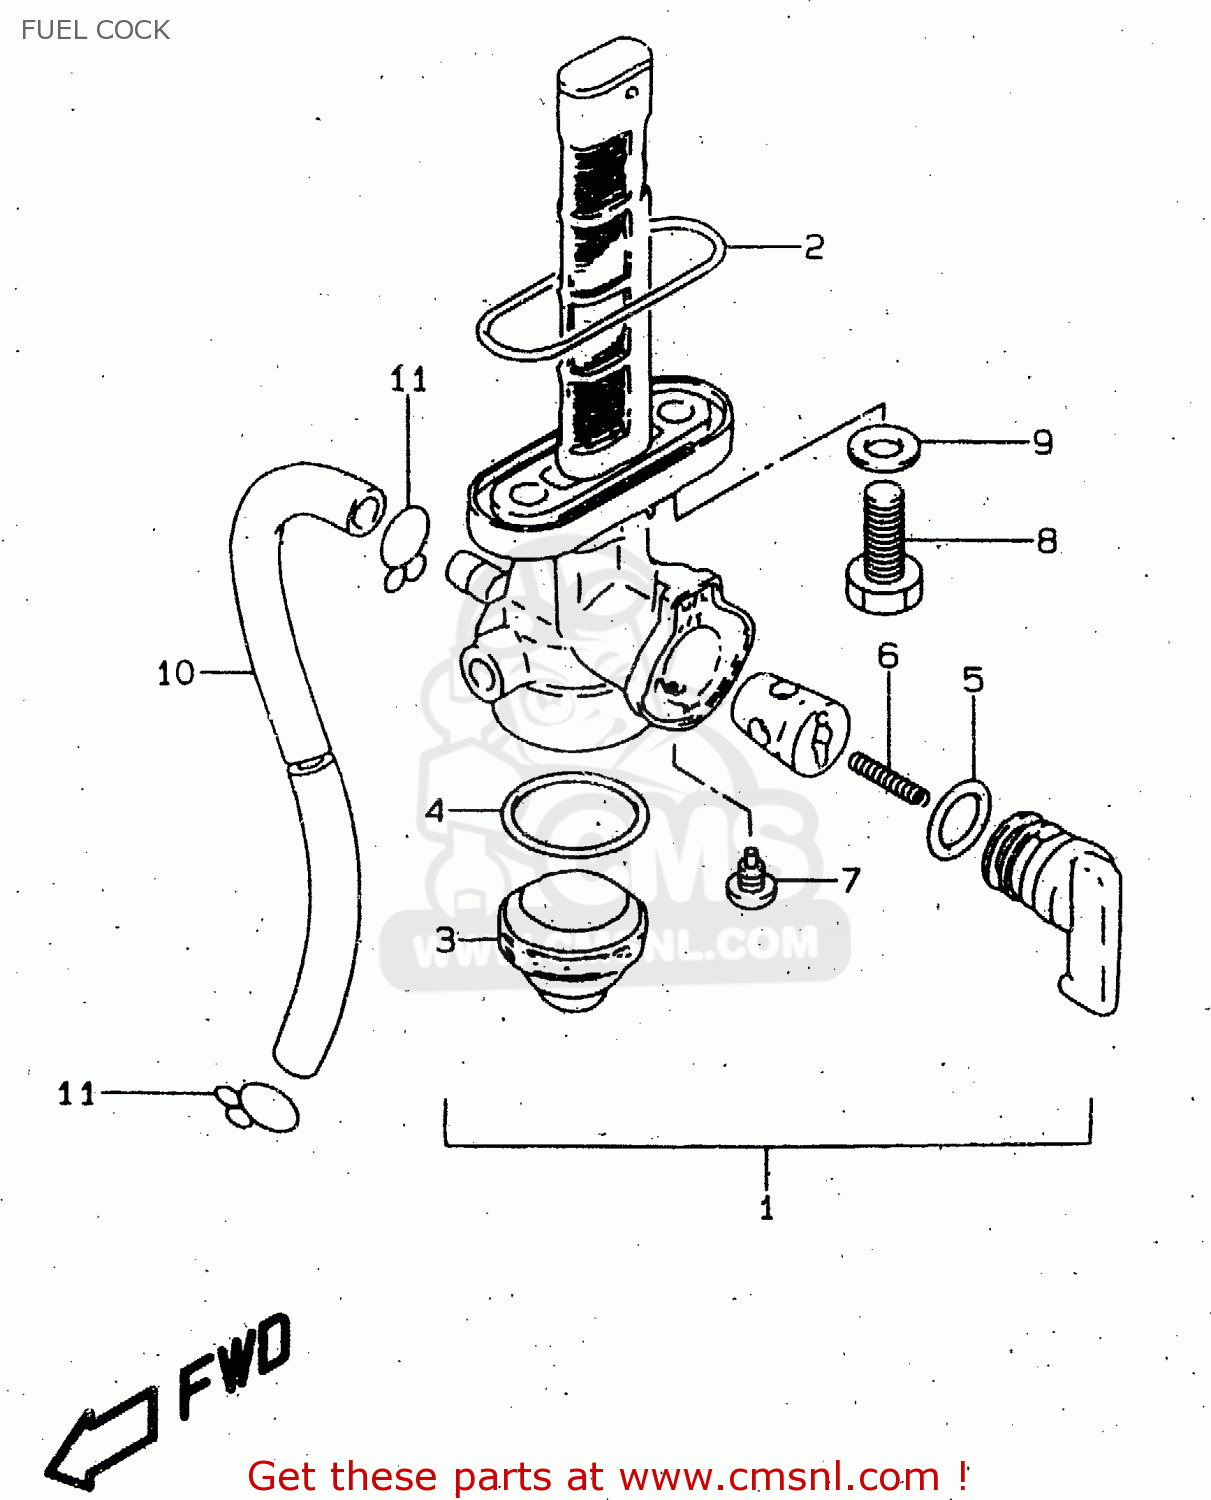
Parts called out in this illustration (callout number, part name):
1	COCK ASSY,FUEL
2	O RING,FUEL COCK
3	CUP,STRAINER
4	GASKET,FILTER (NAS)
5	O RING,LEVER
6	SPRING
7	SCREW
8	BOLT(6X20)
9	GASKET(6.4X11.5X0.8) (NAS)
10	HOSE(5X8.2X600)
11	CLIP
